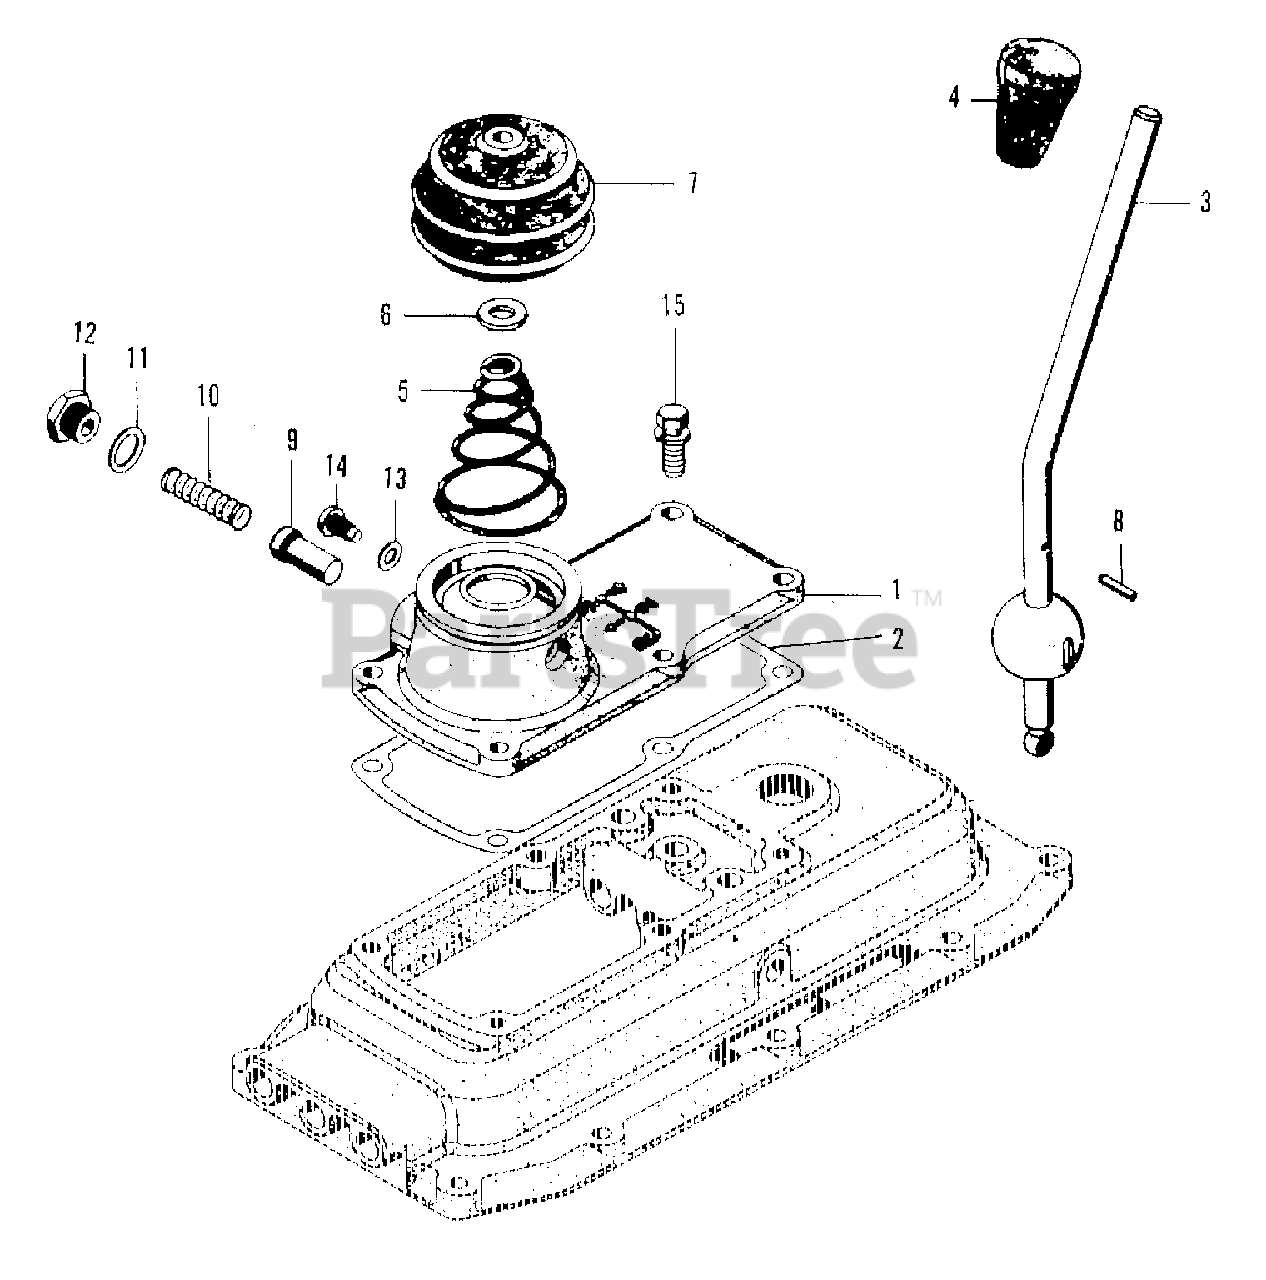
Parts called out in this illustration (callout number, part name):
1	CONTROL, cover
2	GASKET, control cover
3	LEVER, shift
4	KNOB, shift lever
7	COVER, dust
8	PIN, M4 x 20 lock
12	SCREW, lock
14	SCREW, lock
15	CAPSCREW, M8 x 25, w/lockwasher (Seal lock No. 10)
